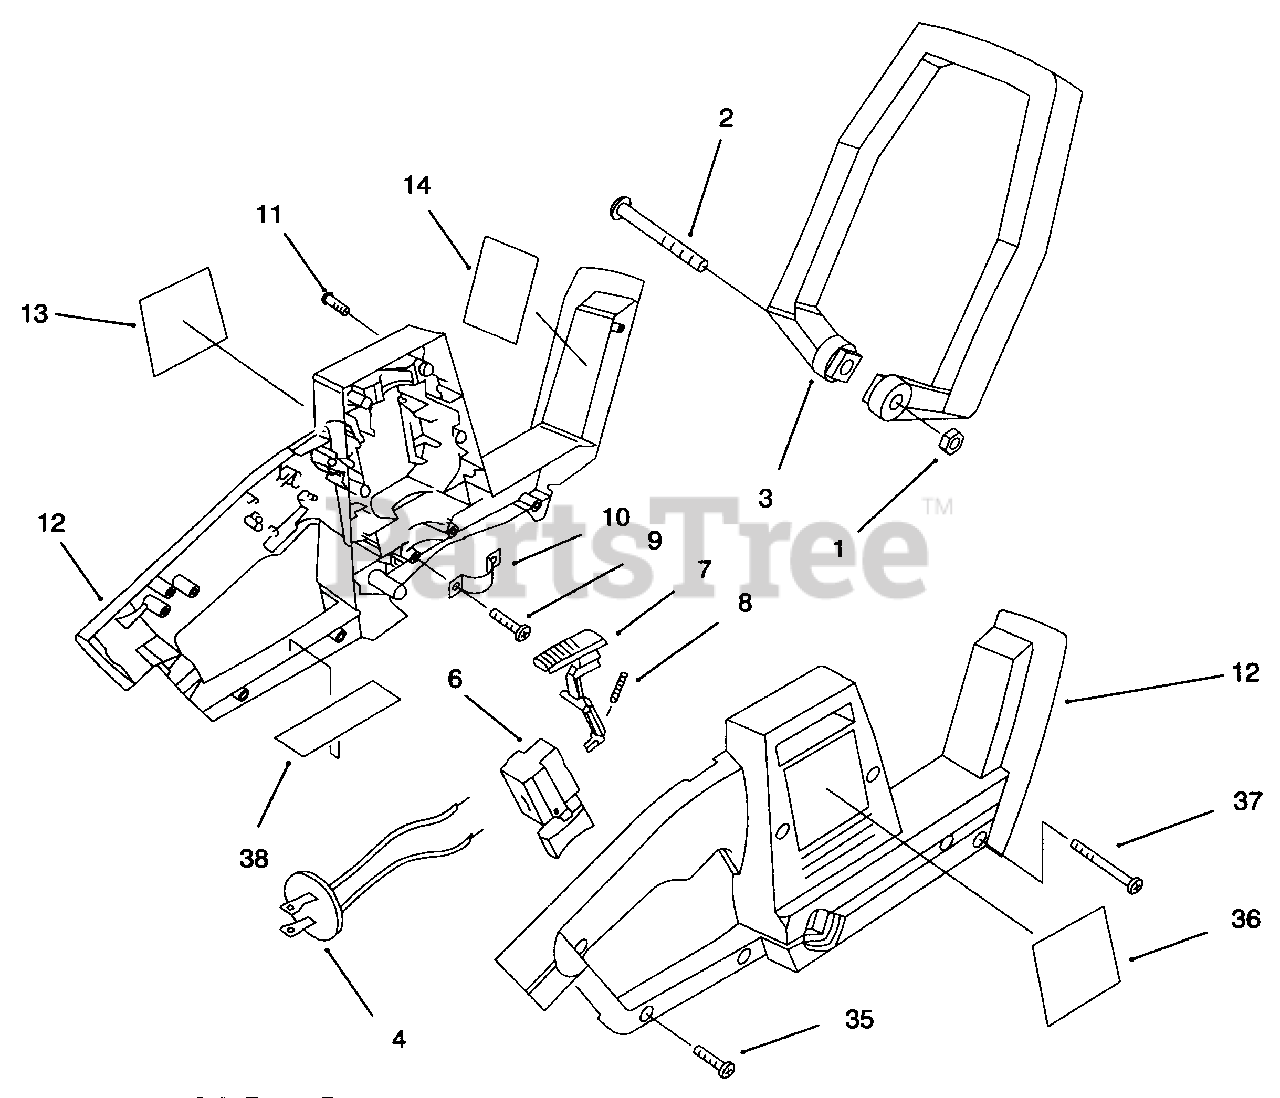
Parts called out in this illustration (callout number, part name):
1	HEX NUT
3	FRONT HANDLE
4	DISC ASSEMBLY
7	LOCK-OFF BUTTON
10	BEARING STRAP
12	HOUSING ASSEMBLY
13	LOGO PLATE (51803)
14	DANGER LABEL
36	WARNING LABEL
38	DATA PLATE (51803)
